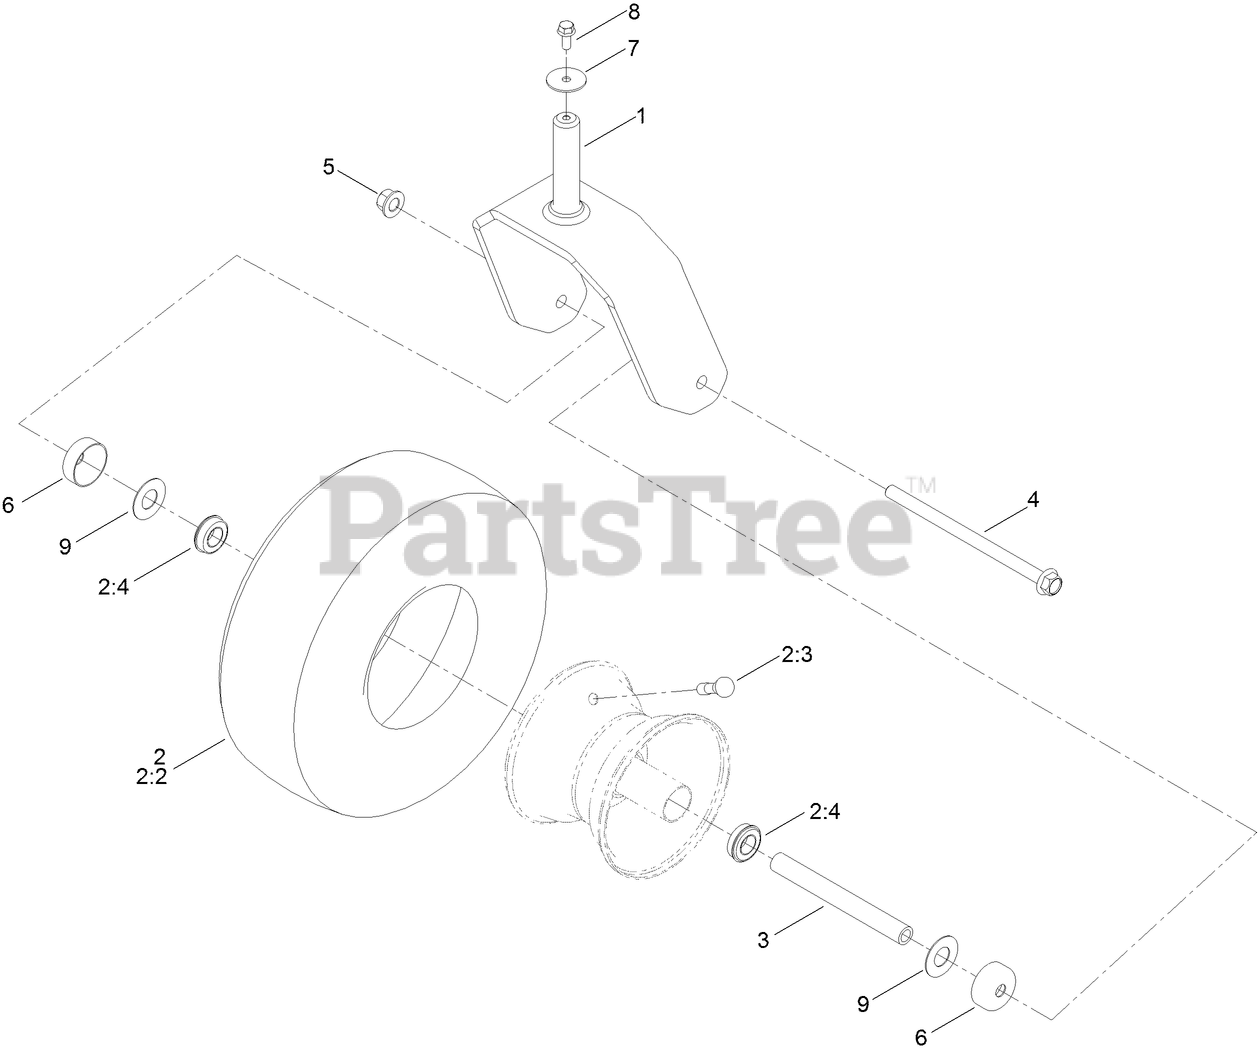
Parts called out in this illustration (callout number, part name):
1	FORK-CASTER
2	TIRE AND WHEEL ASM
2:4	BEARING
3	SPANNER-WHEEL
4	SCREW-HHF
5	NUT-HF
6	GUARD-SEAL
7	WASHER-FLAT
8	SCREW-HHF
9	WASHER
